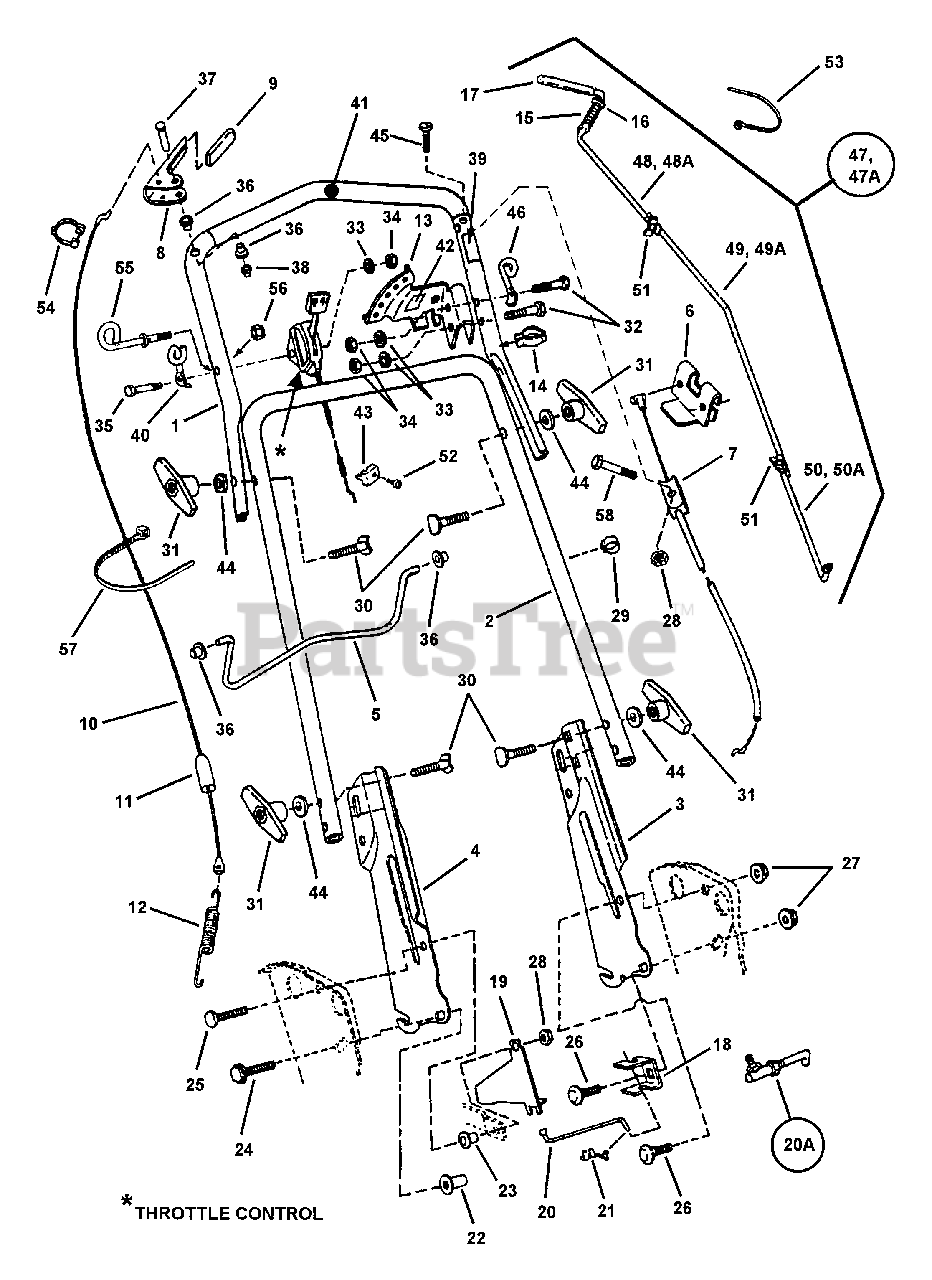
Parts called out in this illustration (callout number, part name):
1	HANDLE, Upper
2	HANDLE, Middle
3	HANDLE, Lower Left Hand
4	HANDLE, Lower Right Hand
5	BAIL, OPC Control (12.2" Wide)
5	BAIL, OPC Control (12.5" Wide)
6	CLIP, Blade Control
7	CABLE, Blade Control (50-1/2" Long)
7	CABLE, Blade Control (74-1/16" Long)
7	CABLE, Blade Control (46-1/16" Long)
7	CABLE, Blade Control (60" Long)
7	CABLE, Blade Control (49-1/4" Long)
8	HANDLE, Wheel Drive
9	GRIP, Wheel Drive Handle
10	CABLE, Clutch Pull (Z-BEND) (41-7/16" Long)
10	CABLE, Clutch Pull (Z-BEND) (36-1/16" Long)
11	COVER, Vinyl
12	SPRING, Clutch
13	SECTOR, Speed
14	TIE, Wire (3)
15	SPRING, Speed Control
16	WASHER, 3/8" Flat
17	GRIP, Speed Control Handle
18	ANCHOR, Speed Control
19	GUIDE, Lower V-Belt
20	ROD, Transfer
20A	ASSEMBLY, Transfer Rod
21	CLIP, Transfer Rod
22	TEE-NUT, 5/16-18
23	BUSHING, Differential
24	BOLT, 5/16-18 x 3/4" Flange Lock, Grade 5
25	SCREW, 5/16-24 x 1" Hex Cap, Grade 5
26	BOLT, 5/16-18 x 5/8" Carriage, Grade 5
27	NUT, 5/16-18 Hex Flange Lock, Grade 5
28	NUT, 5/16-24 Center Lock, Grade 5
29	CLIP, Cable/Wiring
30	SCREW, 5/16-18 x 1-7/8 Curved Head, Grade 2
31	T-KNOB, 5/16-18
32	SCREW, 1/4-20 x 1-1/2 Hex Cap, Grade 5
33	WASHER, 1/4 Internal Tooth Lock
34	NUT, 1/4-20 Hex, Grade 5 or B
35	SCREW, 1/4-20 x 2" Hex Cap, Grade 5
36	BUSHING
37	PIN, 1/4" X 1-1/2"
38	PUSH-NUT, 1/4"
39	DECAL, Blade Control (L.H. Side)
39	DECAL, Operator's Presence Control
39	DECAL, Handle International Warning
40	GUIDE, Rope
41	GRIP, Foam 12"
41	GRIP, Foam 13.5"
42	DECAL, Speed Select
43	CLAMP, Casing
44	WASHER, 5/16 Internal Tooth Lock
45	SCREW, 5/16-24 x 1-1/2" Machine, Grade 5
46	GUIDE, Rope
47	ASSEMBLY, Speed Control Lever
47A	ASSEMBLY, Speed Control Lever
48	ROD, Upper
48A	ROD, Upper
49	ROD, Intermediate
49A	ROD, Intermediate
50	ROD, Lower
50A	ROD, Lower
51	NUT, 1/4-20 Wing
52	SCREW, #10-32 x 5/8" Self-Tapping
53	TIE, Wire
54	CLAMP
55	GUIDE, Rope
56	NUT, 1/4-20 Nyloc
57	CABLE-TIE, 7"
58	SCREW, 1/4-20 x 1-1/2" Hex Head Cap, Grade 5
